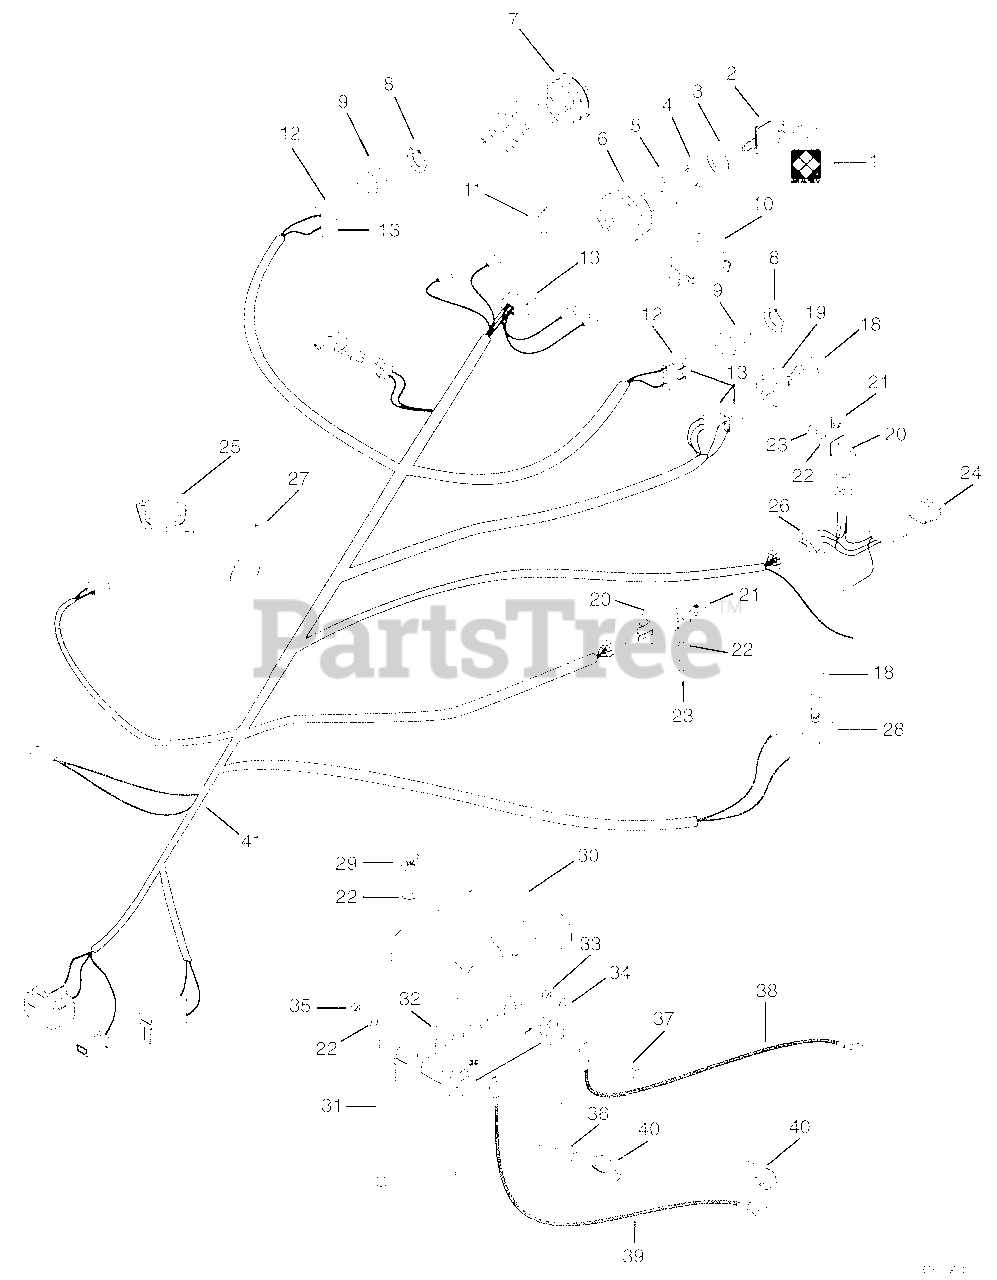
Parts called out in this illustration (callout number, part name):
1	Key Chain
2	Ignition Switch Key
3	Cap Ignition Switch
4	Nut Panel .562-24
5	Washer Lock Internal .563 X .040
6	Ignition Switch
7	Gauge Ammeter
8	Nut Stamped .56-18
9	Switch, Neutral Start N.O.
10	Hour Meter
11	Light, Indicator (003, 004)
12	Connector, 2-Wire Switch
13	Terminal
15	Fuse, 25 AMP
16	Assembly, Connector Weather Tight
17	Terminal, For 10-12 Ga Wire
18	Nut .50-27
19	Switch Assembly
20	Relay
21	Nut Speed .25-20
22	Washer Flat Steel .382 X 1.25 X .134
23	Bolt Hex .25-20 X .63
24	Module, Time Delay
25	Switch, Seat4
26	Adapter Harness (010, 011)
27	Tie Wrap, Black
28	Switch Assembly
29	Nut Wing .250-20
30	Cover, Battery
31	Bolt Round Head Square Neck .25-20 X 7.00
32	12 Volt Battery (8 HP)
33	Nut Locking Nylon .312-18 Grade 2
34	Washer Flat Steel .344 X .688 X .065
35	Nut Locking Nylon .250-20 Grade 2
36	Bolt Hex .25-20 X .75 Grade 5
37	Bolt Hex .31-18 X 1.00 Grade 5
38	Cable, Negative Battery (007, 008, 009, 012, 302)
39	Cable, Battery To Solenoid (007, 008, 009, 012, 302)
40	Boot Insulator
41	Harness, Wiring (007, 008, 009, 012, 302)
